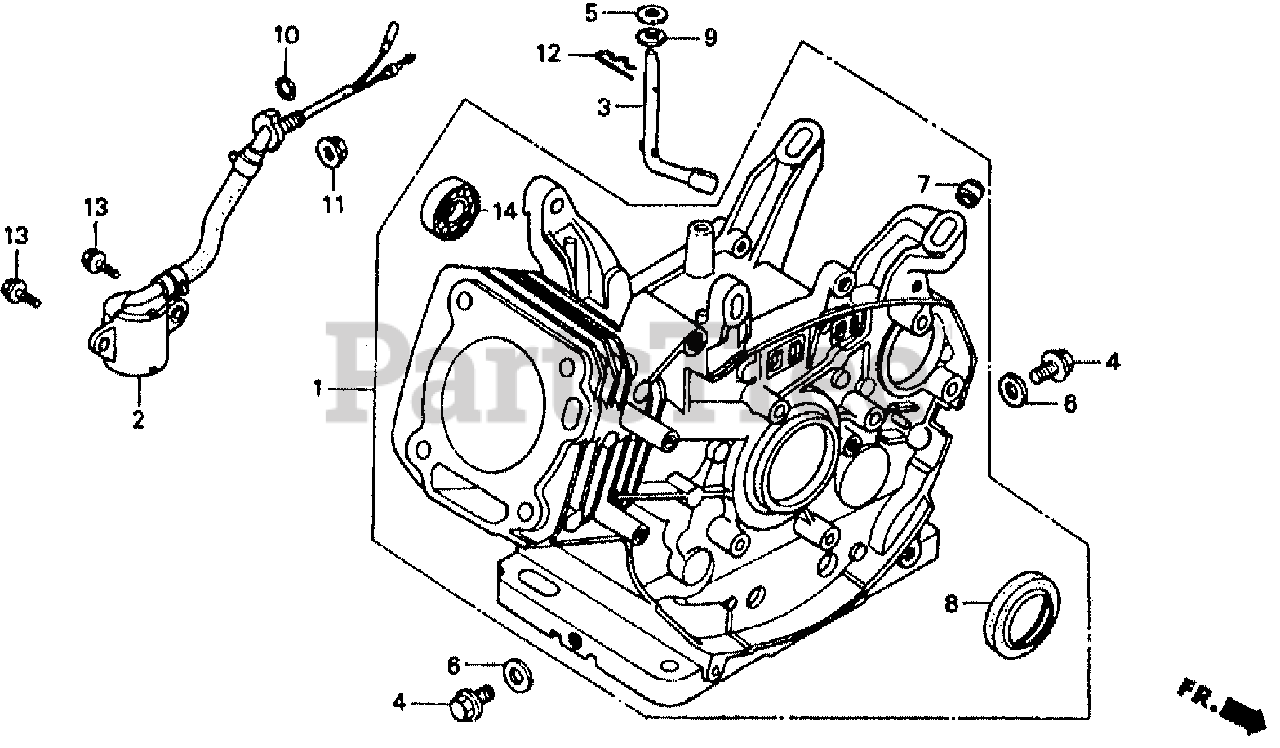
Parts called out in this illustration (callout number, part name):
1	CYLINDER ASSY. (Honda Code 7759624). (BALANCER+OIL ALERT)
2	SWITCH ASSY., OIL LEVEL
3	SHAFT, GOVERNOR ARM
4	BOLT, DRAIN PLUG
5	WASHER (8.2X17X0.8)
6	WASHER, DRAIN PLUG (12MM)
8	OIL SEAL (30X46X8)
9	OIL SEAL (8X14X5)
10	O-RING (13.5X1.5) (ARAI)
11	NUT, FLANGE (10MM)
12	PIN, LOCK (8MM)
13	BOLT, FLANGE (6X12)
14	BEARING, RADIAL BALL (6202)
